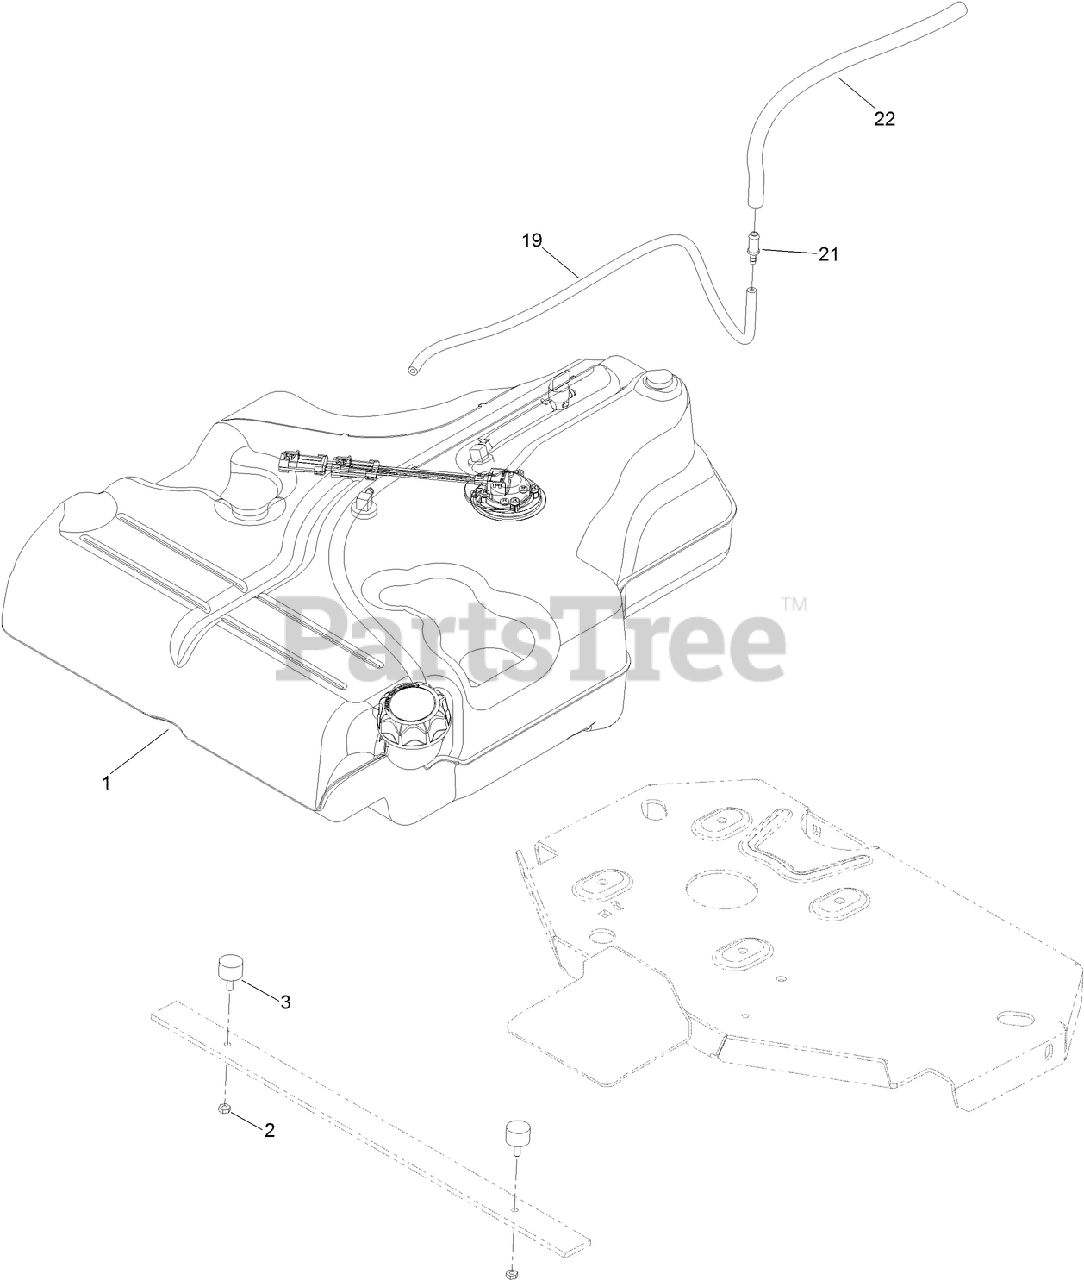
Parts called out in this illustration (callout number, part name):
1	FUEL TANK ASM
2	NUT-JAM
3	BUMPER
19	HOSE-FUEL
21	FITTING-STRAIGHT
22	HOSE-FUEL
